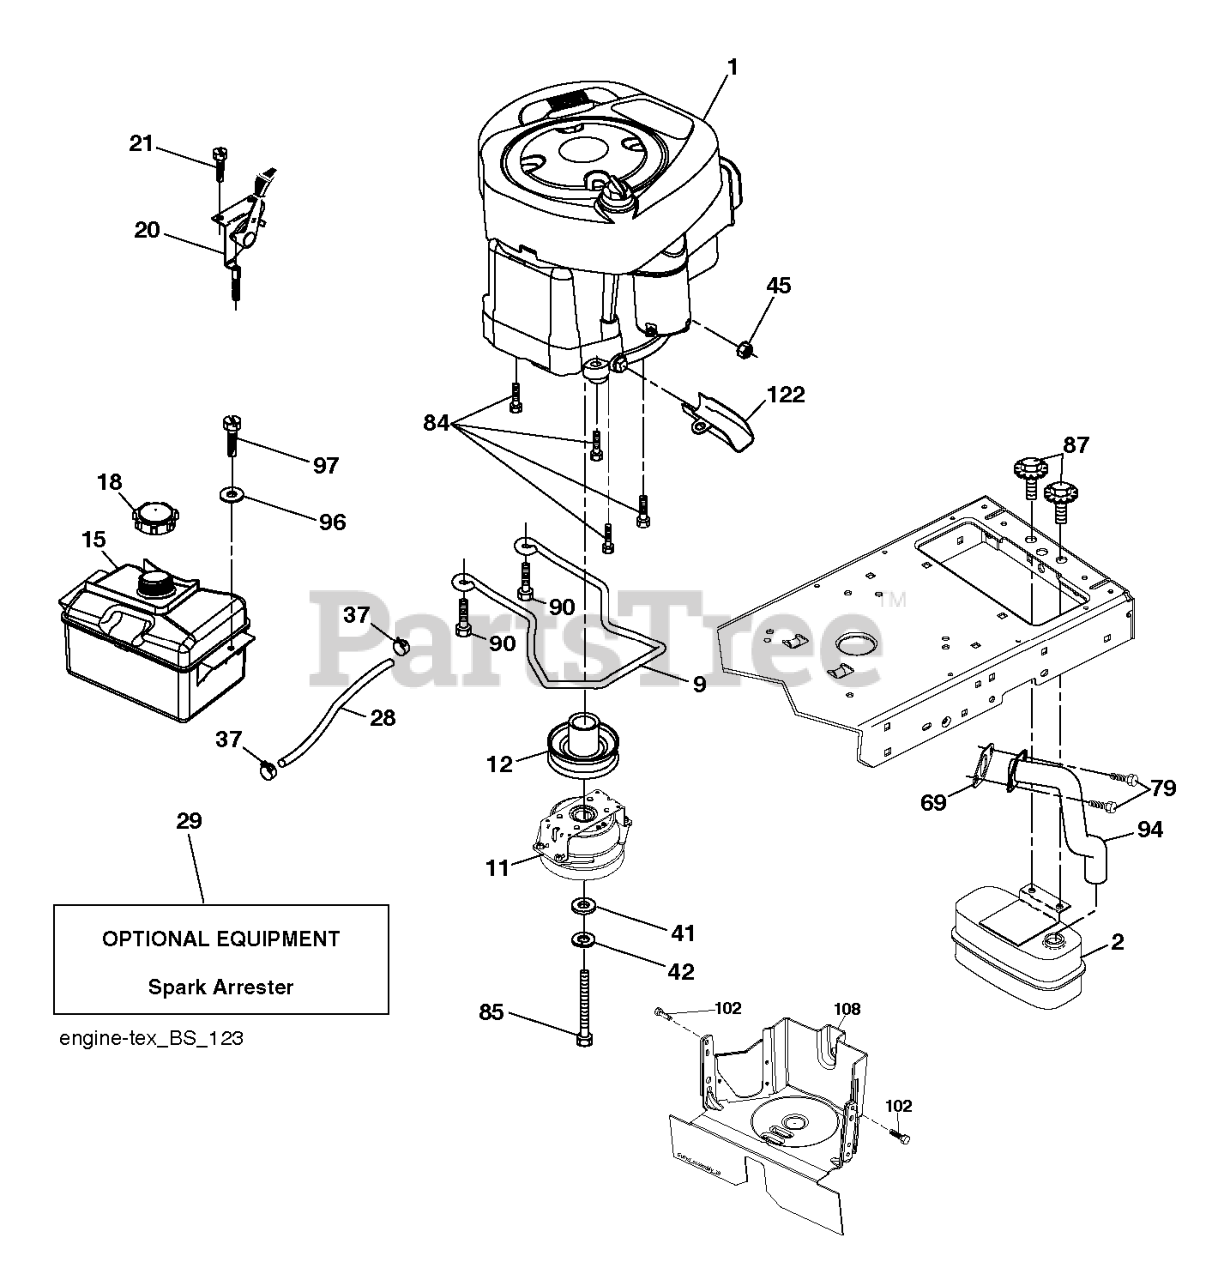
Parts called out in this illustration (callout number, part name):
2	MUFFLER.SINGLE.CYL.KOHL/B&S
9	KEEPER.BELT.ENG.4.25"2.BLT.431
11	CLUTCH.OGURA.5.0PD.GT1.5A-EH07
12	PULLEY.ENGINE.TUFFTORQ
15	FUEL.TANK.ASM.NON-EPA
18	CAP ASM.FUEL.2.25"FR.
20	THROTTLE.COBRA.21".RSTART.BLK
21	SCREW.#10 X 0.750.BOS
28	LINE.FUEL.20
29	KIT.SPARK ARRESTOR 794945 B&S
37	HOSE CLAMP
42	LOCKWASHER
45	NUT
69	REPL BY 532 27 22-93
79	SCREW.SOCKET HD.5/16-1
84	SCREW.3/8-16
85	BOLT.HEX.7/16-20X3.75.GR5.RED
87	BOLT.5/16-18UNCX3/4 W/SEMS.BLK
90	SCREW 3/8-16X1
94	EXHAUST.TUBE.B&S.28/31
97	SCREW HEXWSHR 1/4-20X3/4
102	SCREW 5/16-18X1
108	COVER.PULLEY.ENGINE.W/SHIELD
122	EXTENSION DRAIN OIL
